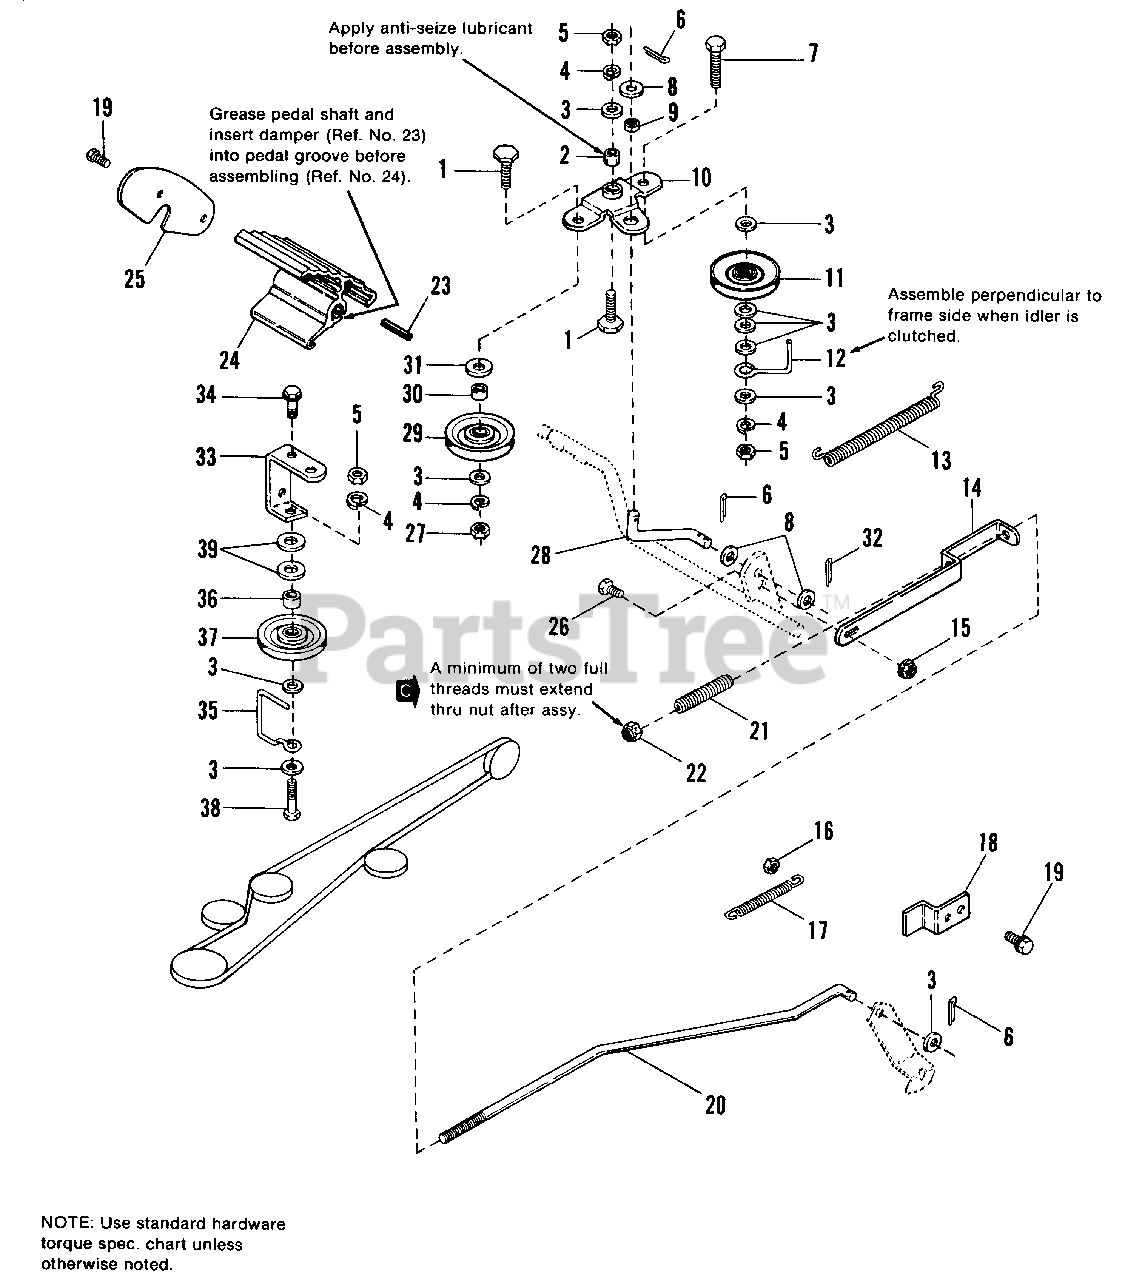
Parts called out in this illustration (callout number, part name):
1	SCREW, Hex, 3/8-16 x 1-1/4, Thin, Hd.
3	WASHER, Plain, 5/16
4	LOCKWASHER, 3/8
5	NUT, Hex, 3/8-16
6	PIN, Cotter, 3/4
7	CAPSCREW, Hex Hd., 3/8-16 x 1-3/4
8	WASHER, Plain, 13/32 x 7/8, 14 Ga.
9	BUSHING, Ball
10	ARM ASSY., Clutch
11	PULLEY, Idler
13	SPRING, Tension, Clutch
15	NUT, Hex, Flange Lock, 3/8-16
16	NUT, Jam Lock, 3/8-16
17	SPRING, Brake Return
18	STOP, Brake Lever
19	SCREW, Taptite, 1/4-20 x 5/8
20	ROD, Brake
22	NUT, Hex Lock, 5/16-18
23	DAMPER, Rubber
24	PEDAL, Foot
25	PLATE, End
26	CAPSCREW, Hex, 3/8-16 x 3/4
27	NUT, Hex, Jam, 3/8-16
28	LINK, Clutch Arm
29	PULLEY ASSY.
31	WASHER, 13/32 x 1, 10 Ga. Plain
32	PIN, Cotter, 1
33	BRACKET, Idler
34	SCREW, Taptite, 5/16-18 x 1/16
38	CAPSCREW, 3/8-16 x 1-3/4
39	WASHER, 13/32 x 1
